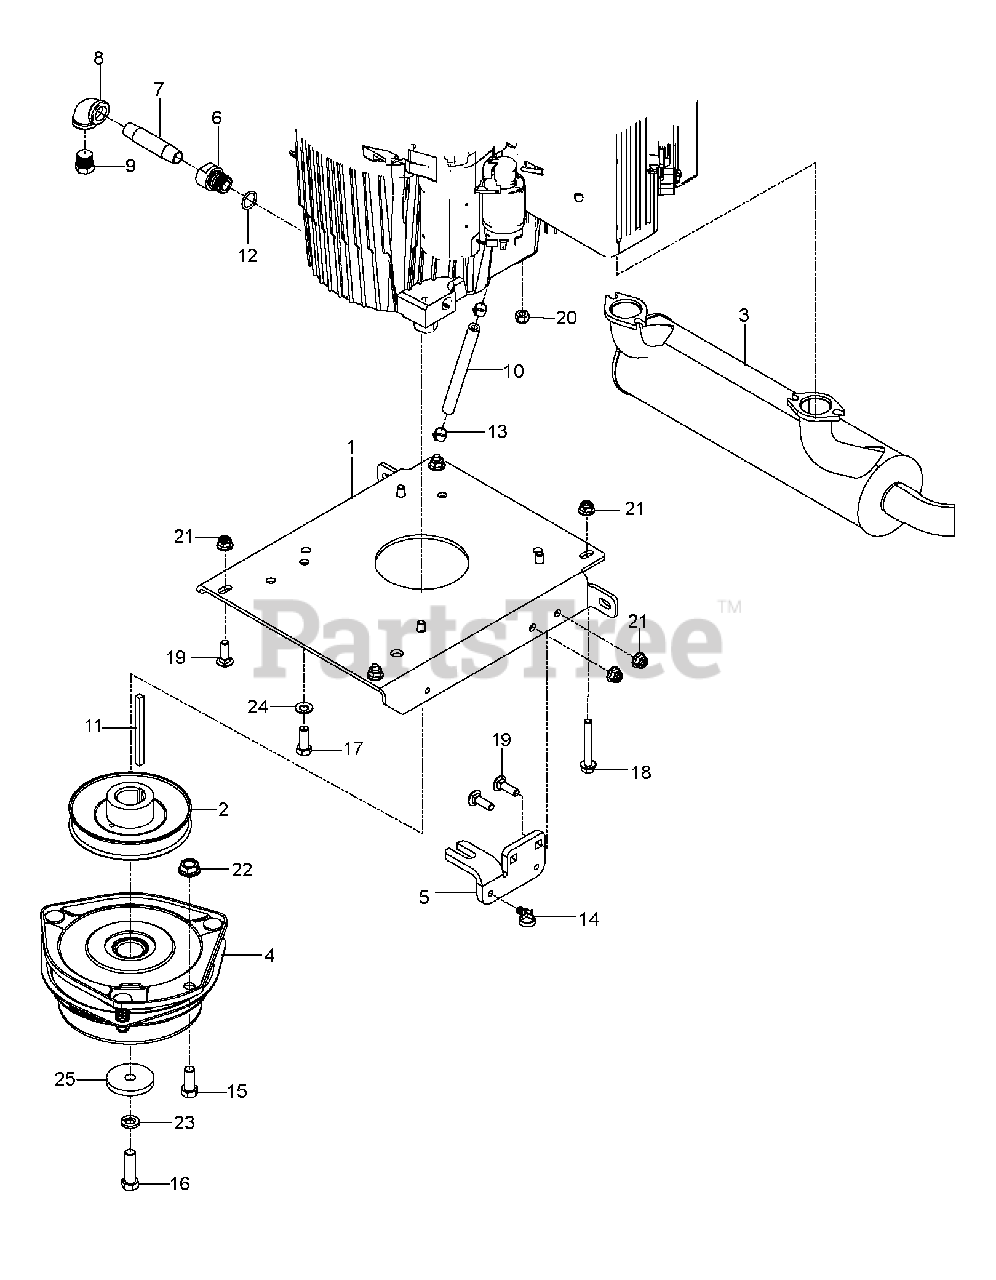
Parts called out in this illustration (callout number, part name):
1	PLATE.ENGINE.BLACK
2	PULLEY, ENGINE
3	MUFFLER, 34HP KAW FX921V-1000V
4	CLUTCH, GT3.5
5	STOP, CLUTCH, OGURA
6	ADAPTER, OIL DRAIN
7	PIPE NIPPLE 3/8 X 3
8	90 DEG.ELBOW 3/8NPT
9	PLUG, DRAIN 3/8 NPTF
10	GAS LINE 10"
11	KEY, 1/4 SQ X 3.5
13	HOSE CLAMP
14	TIE WRAP, 8-3/8", W/CLIP
15	HCS 7/16-14 X 1 GR 5 ZD
16	HCS 7/16F X 1 1/2
17	HCS 3/8-16X1.GRD.5.ZD
18	HHFS 5/16-18 X 2.25 GD 5
19	RHSNB 5/16C X 1
20	NUT M8-1.25 TOP NYL GR10 ZD
21	5/16-18 NYLOC FLANGE NUT
22	NUT 7/16C WHIZ
23	WASHER 7/16 LOCK
24	WASHER, 3/8 DISC SPRING SPEC
25	BLADE WASHER
